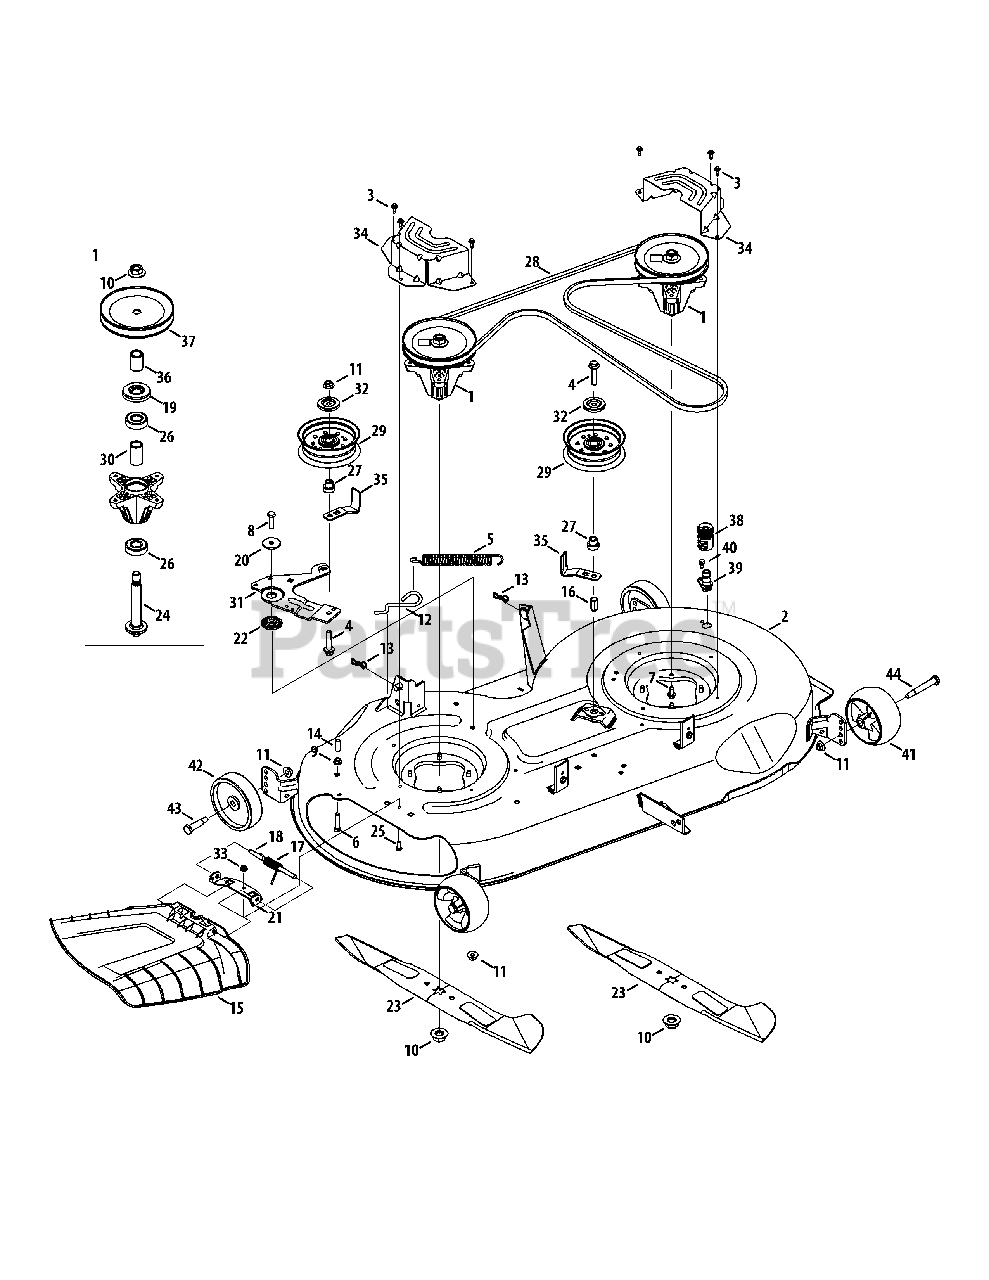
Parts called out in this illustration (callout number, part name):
1	Spindle Ass’y, Pulley, 6.93 Dia
2	Deck, 46"
3	Screw, M6-1 x .625
4	Hex Cap Screw, 3/8-16 x 2.00
5	Extension Spring, .94 Dia. x 7.57
6	Hex Cap Screw, 5/16-18 x 1.50
7	Screw, Self-tapping, 5/16-18, 0.750,
8	Hex Cap Screw, 3/8-16 x 1.25
9	Nut, Flange Lock, 5/16-18, Nylon
10	Nut, Flange, 5/8-18
11	Flange Lock Nut, 3/8-16
12	Deck Spring Rod
13	Bow-Tie Cotter Pin
14	Vinyl Cap, .29 x 1.00
15	Chute Deflector Assembly
16	Rivet Nut, 3/8-16
17	Spring, Torsion, .440 ID x 1.75
18	Hinge Pin
19	Bearing Shield
20	Flat Washer, .39 x 1.5 x .134
22	Shoulder Spacer, .854 x .191
23	Blade, Cut, 23.25" 2-In-1, Cub
24	Shaft, Spindle, 5.75
25	Hex Cap Screw, 1/4-20 x .62
26	Bearing, Ball, .787id x 1.85 Od x .551
27	Shoulder Spacer, Idler
28	Belt, V-Type, A Sec x 108.3
29	Pulley, Idler, 4.50" Dia.
30	Spacer, .792 x 1.060 x 1.860
33	Nut, Flange Lock, 1/4-20, Nylon
35	Belt Keeper
36	Spacer, .800 x 1.10 x 1.470
37	Pulley, Deck, 6.74 Dia.
38	Coupler, Water
39	Deck Wash Nozzle
40	Shoulder Screw, 1/4-20 x 0.50
41	Wheel, Deck, 5.0 Dia. Ball
42	Wheel, Deck 5.0 x 1.38
43	Bolt, Shoulder, .496 x 1.525, 3/8-16
44	Bolt, Shoulder, .496 x 2.50, 3/8-16
